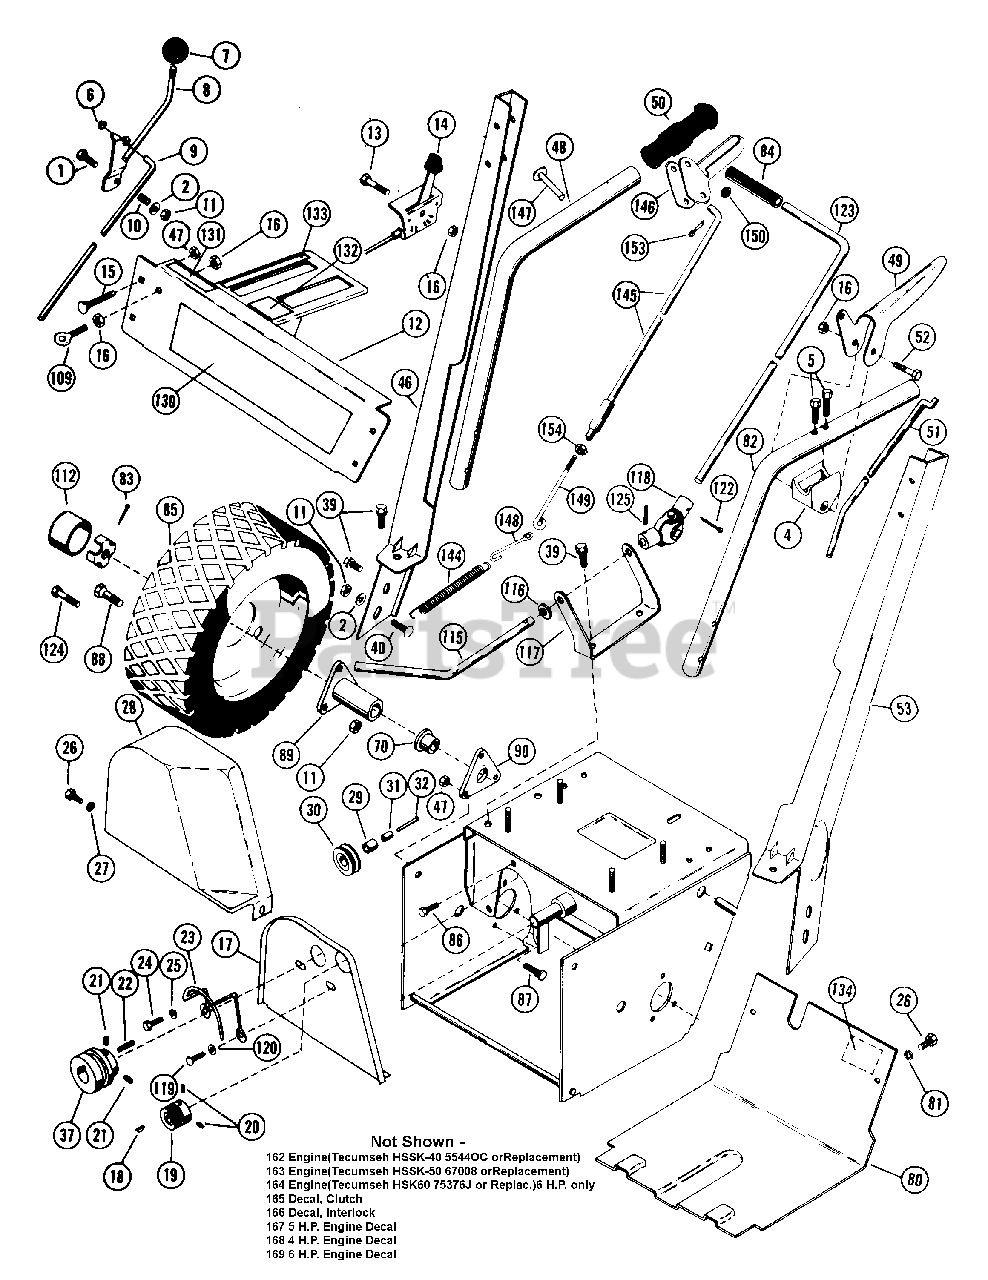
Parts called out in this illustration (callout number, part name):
1	BLT-HEX .31-18X1.50 PL GR2
2	WSHR-FL-STL.312X.734X.065PL
4	HANDLE PIVOT
5	SCR-TAP 12-14X1.50 CROVH PL BT
6	SPRINGGRIP FASTENER
7	SHIFT BALL
8	SHIFT HANDLE
9	SHIFT ROD
10	SG-COMP .105X.585X.75
11	NUT-LK .312-18 GR A PL
12	HANDLEBAR SERVICE ASSEMBLY
13	BLT-HEX .25-20X.75 PL GR2
14	THROTTLE CONTROL
15	BLT-RDHDSQNK .25-20X1.50 SHTPL
16	NUT-LK-CTR .250-20 PL
17	INNER BELT COVER
18	KEY-WDRF .125X.625X.250 SAE5
19	CAMSHAFT SHEAVE
20	SCR-SET .25-20X.25 SKHCUPNY OH
21	SCR-SET .32-18X.38 SKHCUPNL OH
22	KEY-SQ .188X1.0X.188 SAE 8630
23	BELT FINGER
24	BLT-HEX .31-24X.75 PL GR5
25	WSHR-LK .312X.097 PL HVY
26	BLT-HEX .25-20X.50 PL GR2
27	WSHR-FL-STL .250X.562X.049 PL
28	OUTER BELT COVER
29	BSHG-SLV .500X.625X.937
31	IDLER SHAFT
32	RVT-TBLR .187X1.218 OH ST PL
33	WSHR-FL-STL .38X.875X.083 PL
34	PIN-HAIR INT .08X.18X1.18
35	PIN-COTR .09X.75 PL
36	IDLER ARM ASSEMBLY
37	ENGINE SHEAVE
38	CAP, .50 ROD YWZC
39	BLT-SERHFWH .31-18X.50 PL
40	BLT-RDHDSQSHNK .31-18X.50 YZ
41	BLT-HEX .25-20X.38 PL GR2
42	WSHR-LK-EXT. 250 ID
43	NUT-LK-CTR .50-20 PL
44	FRICTION DISC
45	FRICTION DISC HUB
46	R H LOWER HANDLEBAR
47	NUT-LK-FLG .250-20 PL
48	R H UPPER HANDLEBAR
49	CLUTCH HANDLE
50	GRIP
51	CLUTCH ROD
52	BLT-HEX .25-20X1.75 PL GR2
53	L H LOWER HANDLE BAR
54	ROD ADAPTER
56	BSHG-SLV .334 X .502 X 1.437
57	SHIFT LEVER
58	BLT-HEX .31-18X.75 PL GR2
59	BLT-RDHDSQNK .31-18X2.0 SHT PL
60	SHIFT LINK
61	WSHR-FL-STL .505X1.000X.062
62	BEARING RETAINER
63	BRG-BALL .500X1.38X.437
64	CARRIER
65	PIN-ROLL .188X1.00
66	RVT-POP .187X.402 DOME ST
67	HEX SHAFT
68	RVT-POP.125 X .294 DOME
69	BEARING RETAINER
70	BSHG-FLG .750X1.000X.625X1.250
71	TRACTOR FRAME
73	KEY-FTHR .188X1.25X.187 SAE
74	KEY-WDRF .25X.750X.313 SAE91
75	AXLE SHAFT
76	PIN-ROLL .125X1.00
77	RETAINER PLATE
79	SPUR GEAR, FELLOWS 35T .750 ID
81	WSHR-LK .250X.077 HVY PL
82	L H UPPER HANDLEBAR
83	PIN-COTR .12 X 1.25 PL
85	WHL 10.25 IN O.D.
85	TIRE & WHEEL ASSEMBLY
85	TIRE 4.10/3.50-4
85	TUBE
85	T/WHL ASSY 4.80 X 8 AGRI LUG
85	WHL
85	BLT-HEX .38-16X.63 PL GR2
85	WSHR-LK .375X.094 MED PL
85	NUT-HEX .375-16
87	SCR-SLTR-SERNK .25-20X.62 PL
88	BLT-WHL .50-20X.75 GR5 PL
89	WHEEL HUB
90	SUPPORT, BEARING
91	KEY-WDRF .125X.500X.203 SAE 3
92	SPINDLE
93	DRIVE DISK
94	ROD ADAPTER
96	DRIVE SPINDLE HOUSING
97	DEADMAN LEVER
98	BLT-HEX .25-20X.75 PL GR5
99	DEADMAN BRACKET
100	BEARING SPACER .75 X .5 X.88
101	SPINDLE HOUSING
102	DRIVE SHEAVE
103	V-BELT, SPECIAL-RAW EDGE (SET)
105	BLT-HEX .31-18X1.00 PL GR 2
106	RATCHET PLATE
107	ADJUSTMENT LINK
108	SG-TENS .063X.44X2.81 WLD 18
109	ROD HANGER EYEBOLT
111	SPINDLE CUP
112	HUB CAP
113	SG-TENS .125X.437X5.5 WLD 20
115	CLUTCH LEVER ROD
116	WSHR-FL-STL .382X.812X.023 PL
117	SUPPORT BRACKET
118	UNIVERSAL JOINT ASSEMBLY
119	SCR-MCH .31-24X.75 CRFL
120	WSHR-LK-EXT .313X.025
122	PIN-COTR .12X1.0 PL
123	CLUTCH ROD
124	BLT-HEX .31-18X.75 PL GR2
125	PIN-ROLL .125X.75
127	CLEVIS PIN
129	WSHR-FL-STL .250X.562X.125 PL
130	HANDLEBAR DECAL
131	IN-OUT LABEL
132	DECAL WARNING
133	SHIFT DECAL
134	DISK ADJUSTMENT DECAL
135	IDLER ARM ADJUSTMENT DECAL
136	ENG BOLT SPCR
137	BRACKET SWITCH
138	ACTUATOR SWITCH
139	RETAINER ROD
140	WIRING HARNESS
141	MODULE T SERVICE ASSEMBLY
142	SNAP BUSHING-.437
143	SG-TENS 3.75 FREE LENGTH
144	SG-TENS .063X.44X1.56
145	UPPER ROD INTERLOCK
146	HANDLE INTERLOCK
147	PIN PIVOT
148	CONNECTING LINK
149	LOWER ROD INTERLOCK
150	PUSH NUT, .25
153	PIN-COTR .06X.50
154	NUT-HEX .250-20 PL
156	SWITCH BOOT
157	SCR-TAP 10-24X.375 CRPH 1A
158	SCR-TAP 10-24X.25 CRSLPH PL 1A
159	NUT-LK TOP 10-24 PL
160	BLT-HEX 10-24X.38 PL GR2
161	CONNECTOR
162	Engine(Tecumseh HSSK-40 5544OC orReplacement)
163	Engine(Tecumseh HSSK-50 67008 orReplacement)
164	Engine(Tecumseh HSK60 75376J or Replac.)6 H.P. only
167	5 HP ENGINE DECAL
168	4 HP ENGINE DECAL
169	6HP ENGINE DECAL
